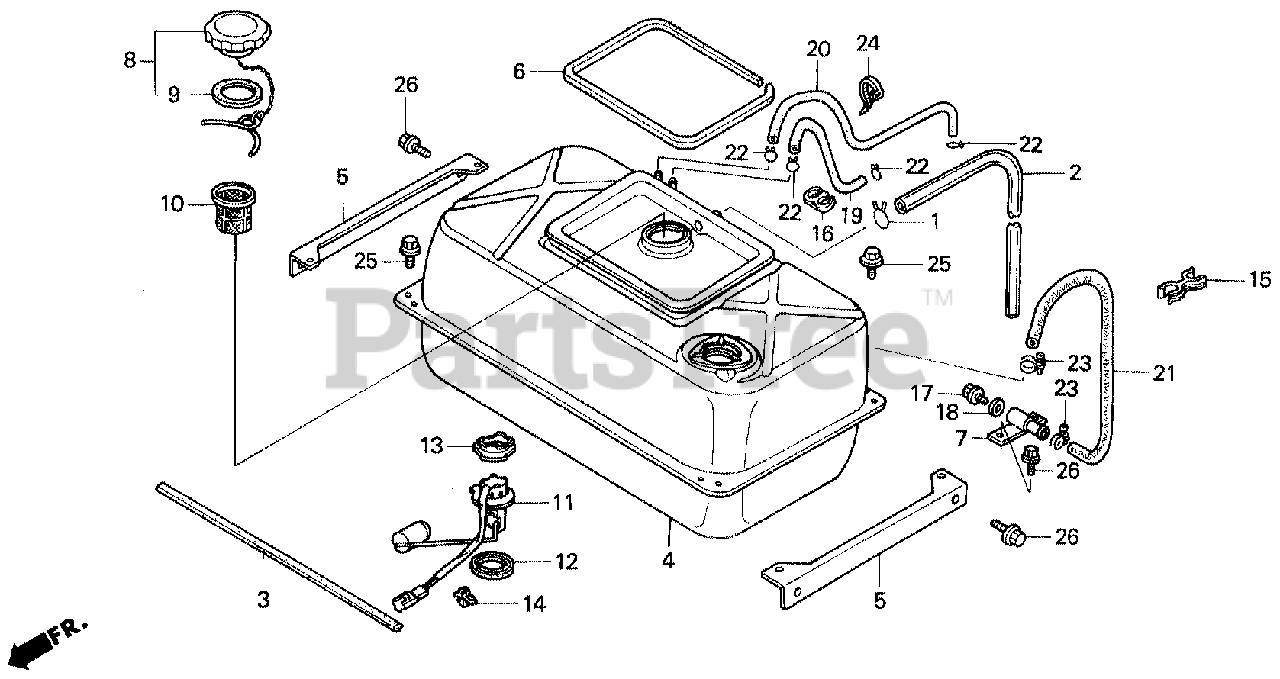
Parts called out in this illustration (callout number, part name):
1	CLIP, BREATHER TUBE
2	TUBE, FUEL DRIP VINYL
3	RUBBER A, FUEL TANK (UPPER)
4	TANK, FUEL *B132* (JOHN BLUE)
5	PROTECTOR, R. FUEL TANK
6	SEAL, FUEL TANK TRAY
7	PLUG, FUEL DRAIN
8	CAP, FUEL FILLER
9	GASKET, FUEL FILLER CAP
10	FILTER, FUEL
11	UNIT, FUEL
12	GASKET, BASE
13	RETAINER, FUEL UNIT
14	CLIP, WIRE HARNESS (8MM) *NH1* (BLACK)
15	HOLDER, FUEL TUBE
16	CLIP, IGNITION WIRE
17	BOLT, DRAIN PLUG (12MM)
18	WASHER, DRAIN PLUG (12MM)
19	BULK HOSE, FUEL (4.5X3000) (4.5X290)
20	BULK HOSE, FUEL (4.5X3000) (4.5X580)
21	BULK HOSE, FUEL (7.5X3000) (7.3X490)
22	CLIP, TUBE (D8)
23	CLIP, TUBE (D13)
24	BAND B1, CABLE
25	BOLT, FLANGE (6X12)
26	BOLT, FLANGE (8X16)
